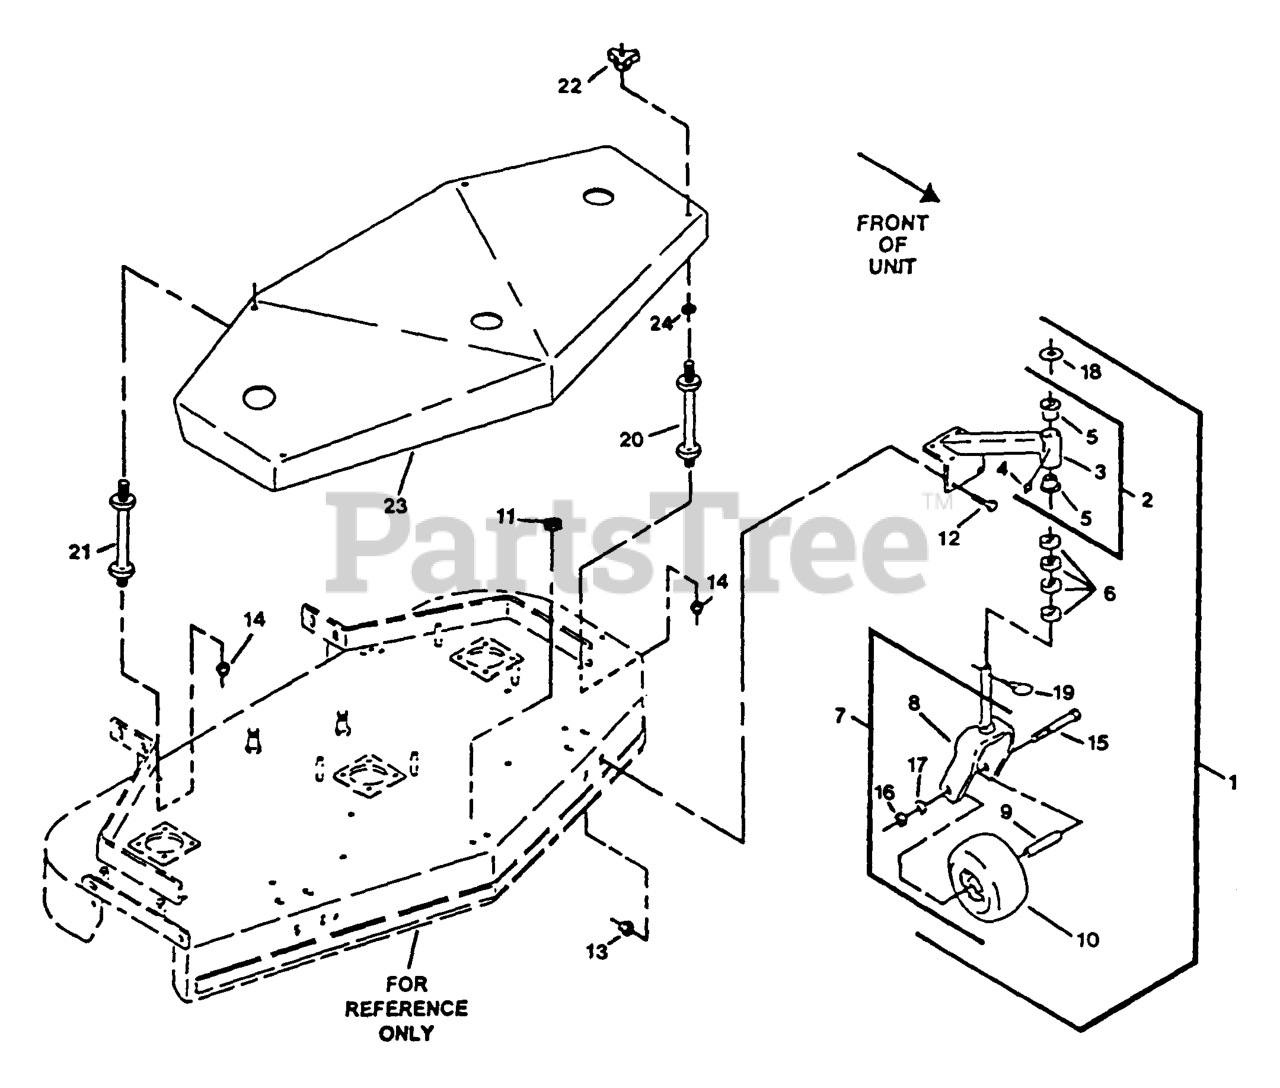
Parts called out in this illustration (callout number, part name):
1	CASTER/MOUNT ASM
2	SUPPORT ASM
5	BEARING-FLANGED
6	SPACER-CASTER
18	WASHER-FLAT
20	STUD-SHIELD, BELT (SHORT)
21	STUD-SHIELD, BELT (LONG)
22	KNOB-3 PRONG
23	ASM,SHIELD BELT 48
